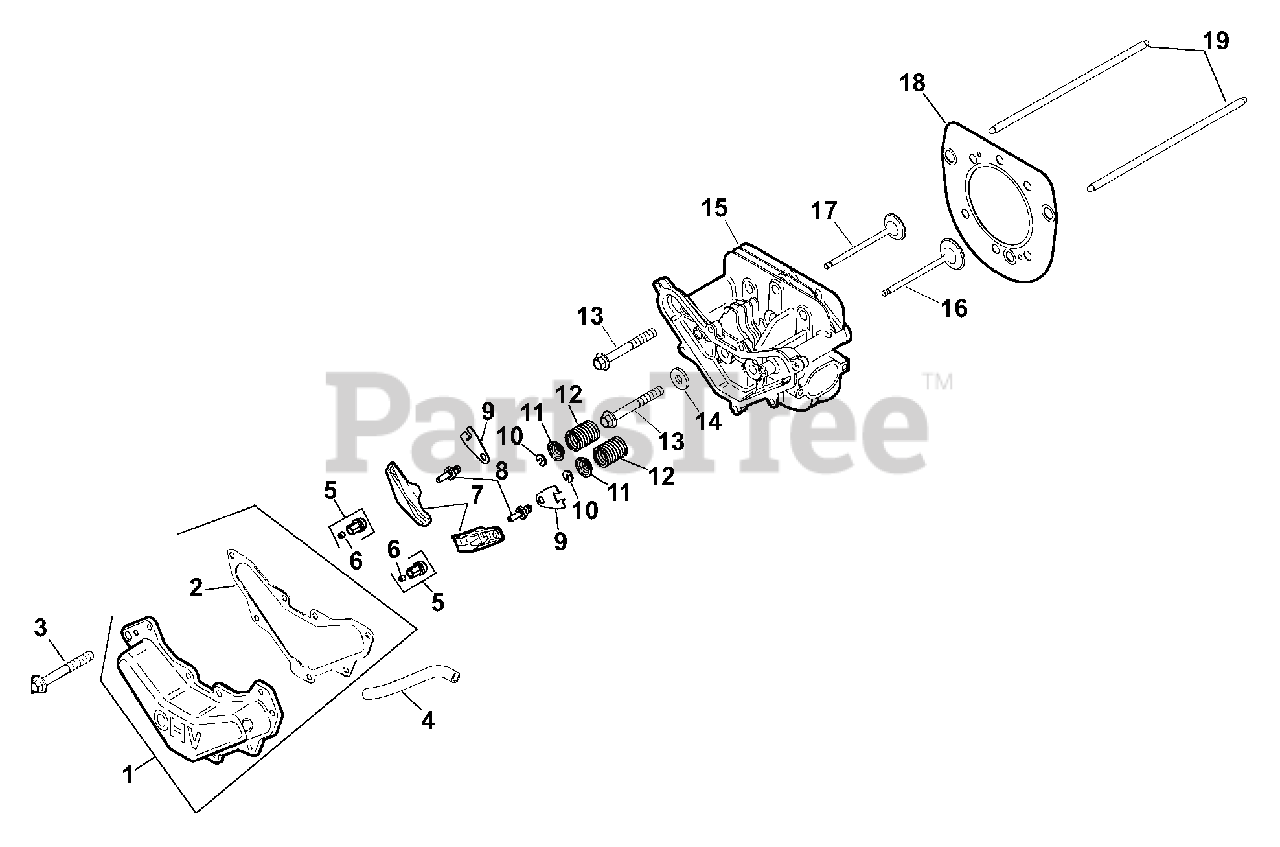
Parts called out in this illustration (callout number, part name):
1	Kit, Valve Cover
2	Gasket, Valve Cover
3	Screw, Flg Thd Frm M6x1.0x20
4	Hose, Breather
5	Pivot, Rocker Arm
6	Screw, Set
7	Arm, Rocker
8	Stud, Rocker
9	Plate, Push Rod Guide
10	Lock, Retainer
11	Cap, Valve Spring
12	Spring, Valve
13	Screw, Flg M1 Ox1.5x80
14	Washer, Flat 13/32"
15	Cylinder Head Assembly
16	Valve, Exhaust
17	Valve, Intake
18	Kit, Cylinder Head Gasket
19	Rod, Push
